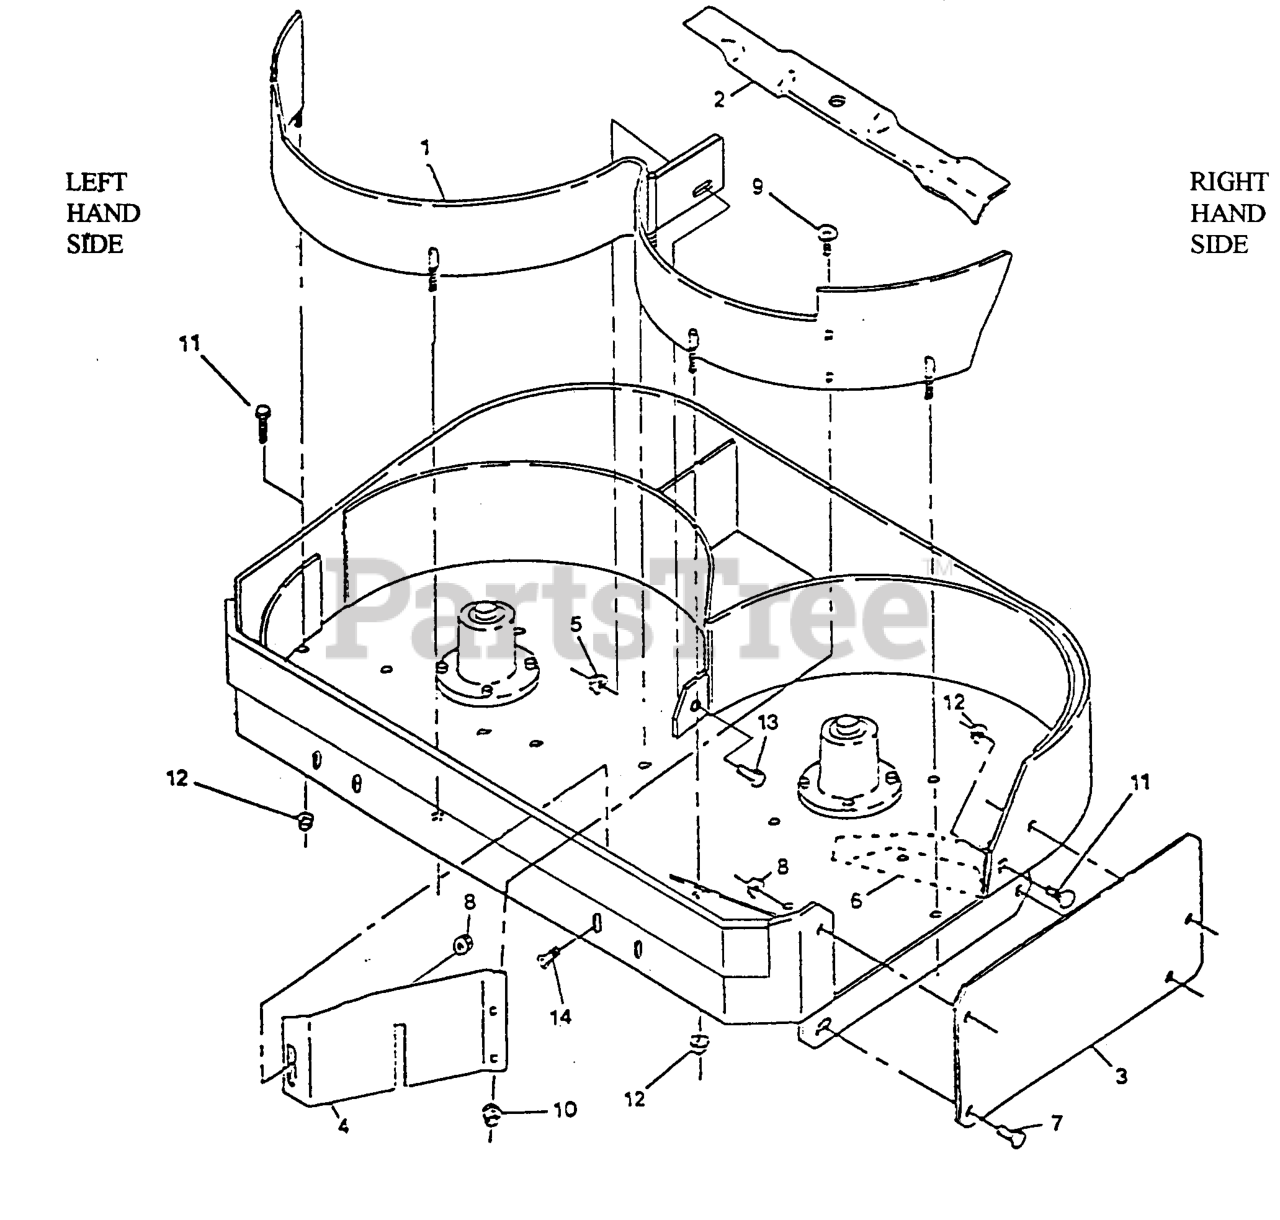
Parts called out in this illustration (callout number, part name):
1	BAFFLE-MULCH
3	PLATE-COVER
6	BAFFLE-DOGLEG
9	BOLT-CARR
